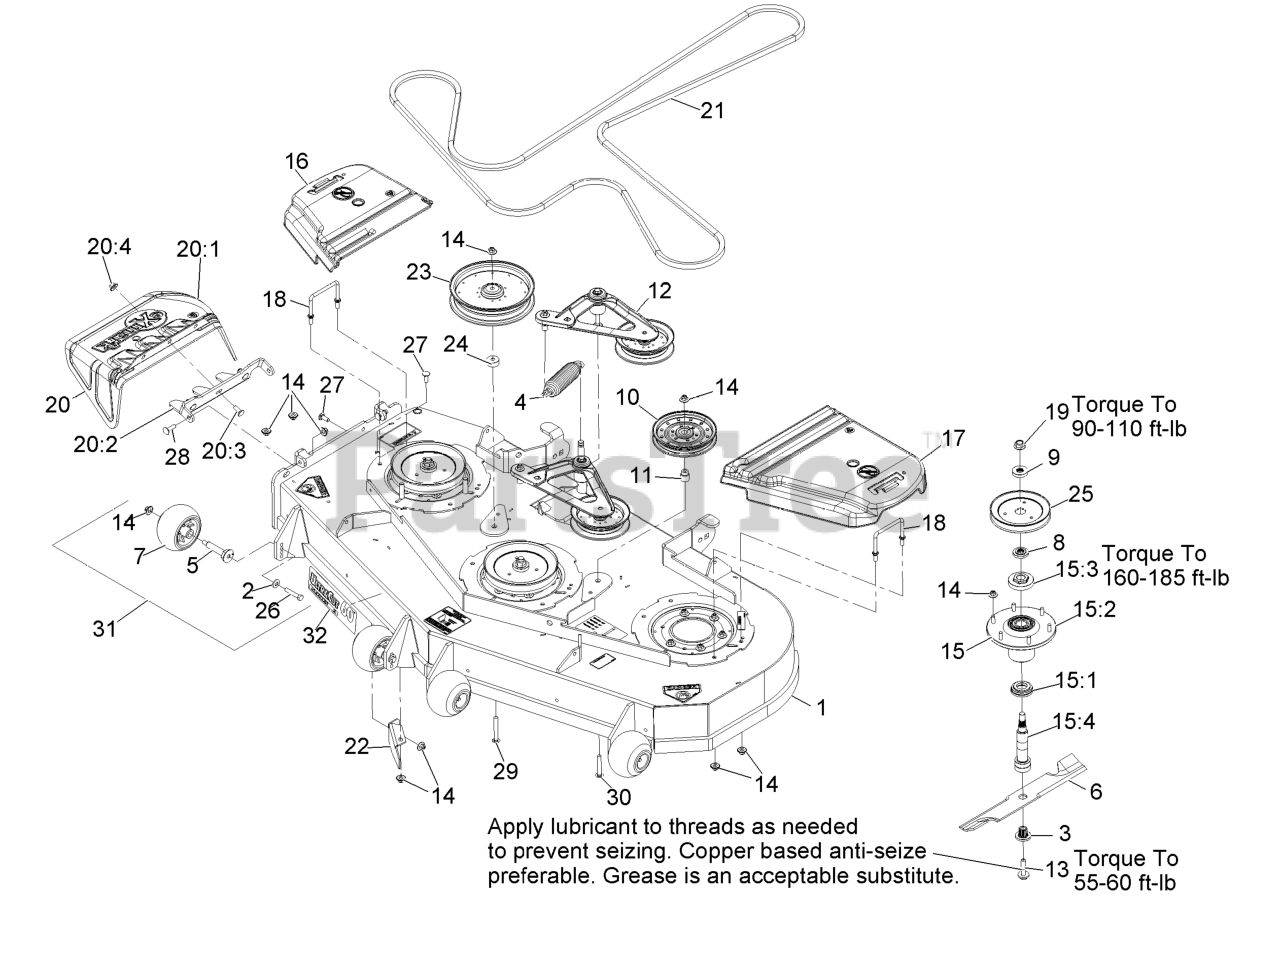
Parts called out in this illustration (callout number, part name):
1	DECK ASM,W/DECALS 60
2	WASHER-BELLEVILLE
3	BUSHING,SPLINED
7	ROLLER-SCALP, ANTI
8	SPACER,SPLINED STEPPED
9	SPACER,SPLINED
11	BUSHING-IDLER
12	DECK IDLER ASM
13	SCREW,SEMS 1/2-20 X 2.19
14	Nut-Nyloc 3/8-16 Flg
15	ASM,SPINDLE HOUSING
15:1	GUARD,BOTTOM
15:2	ASM,CUTTER HOUSING
15:3	NUT, SPINDLE 7/8-14
15:4	SPINDLE,DOUBLE SPLINE
16	COVER-BELT, RH
17	COVER-BELT, LH
18	WIREFORM-COVER
19	NUT-FLANGE, CENTERLOCK
20	ASM,DISCHARGE CHUTE
20:1	CHUTE,DISCHARGE
20:2	BRACKET,DISCHARGE CHUTE
20:3	SCREW-CARR
20:4	Nut-Nyloc 3/8-16 Flg
21	BELT,V-5V-198.75
22	BAFFLE,DISCHARGE 52/60
23	PULLEY-IDLER
24	SPACER-IDLER
25	SHEAVE,BLADE DRIVE 7.25
26	SCREW-HH
27	SCREW-CARR
28	Bolt-Carriage 3/8-16 X 1 1/4
29	SCREW-CARR
30	SCREW-CARR
32	DECAL,ULTRACUT 60 SERIES
